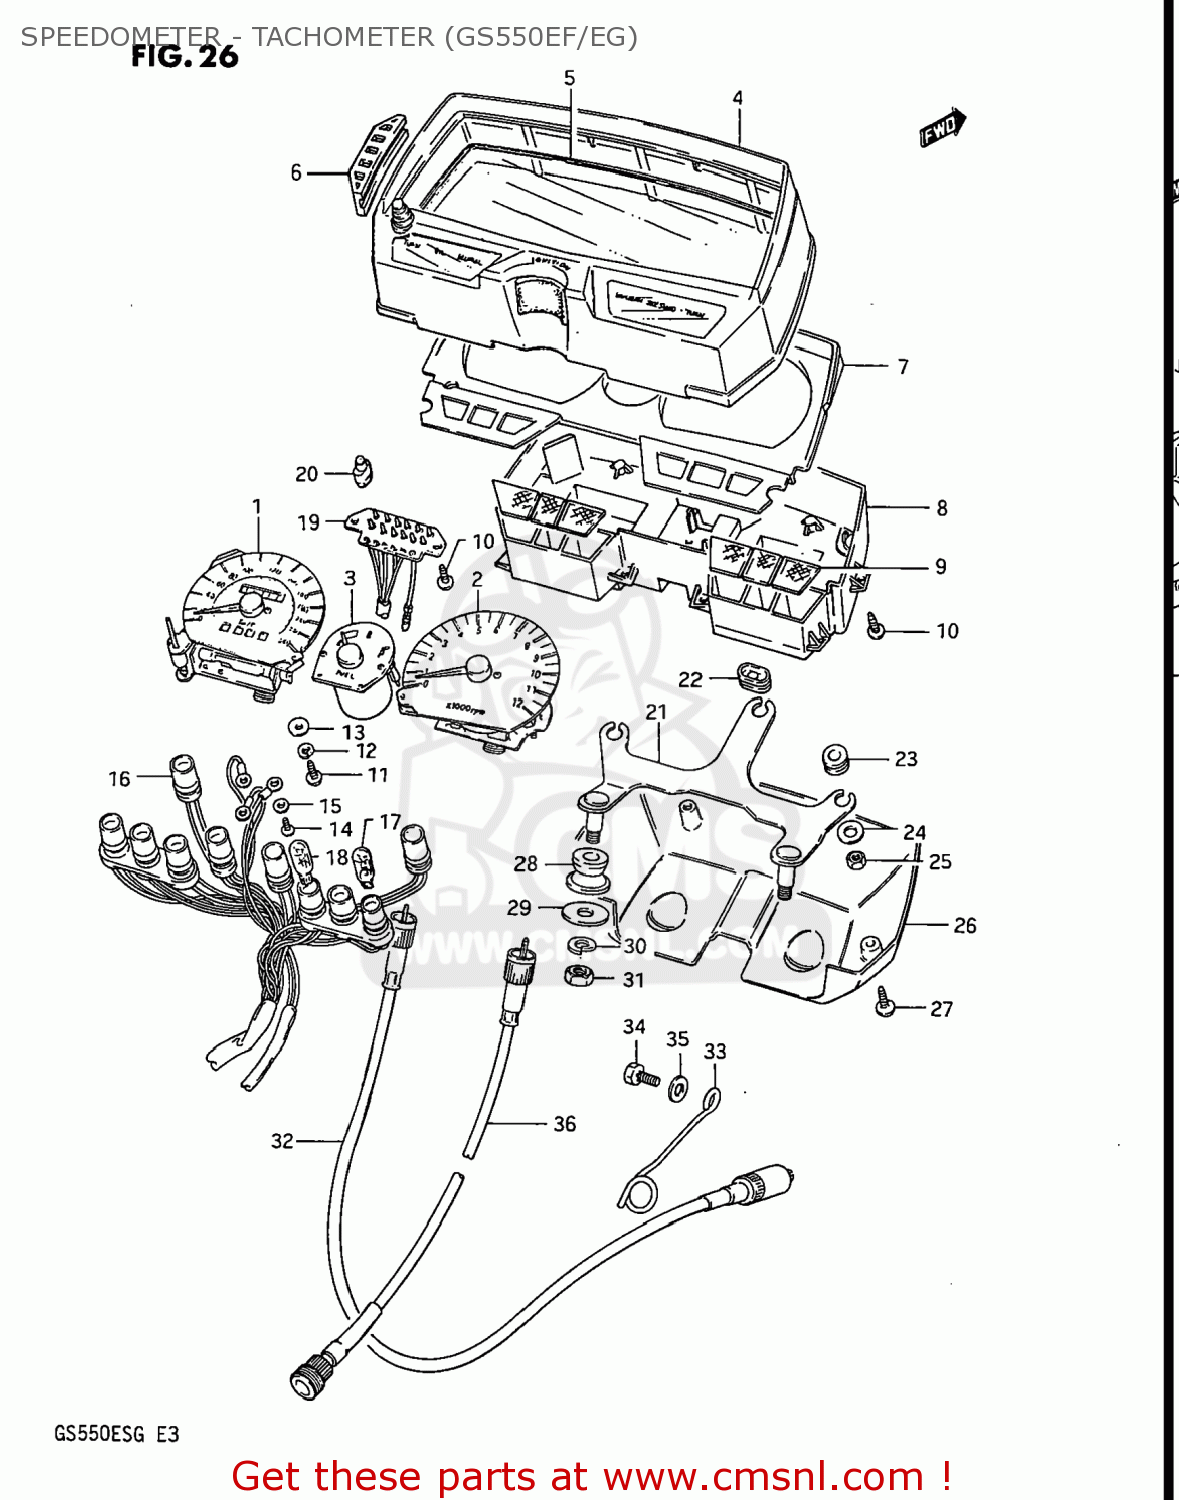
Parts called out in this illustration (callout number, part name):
1	METER,SPEEDOMETER (KM/MPH)
2	METER,TACHOMETER
3	METER,FUEL
4	HOOD,METER
5	GLASS,SPEEDOMETER
6	CUSHION,METER CASE
7	PLATE,METER WINDOW
8	CASE,METER,INNER
9	LENS SET,PILOT
10	SCREW,GEAR INDICATOR
11	SCREW
12	LOCK WASHER
13	WASHER
14	SCREW
15	WASHER
16	SOCKET
17	BULB(12V3.4W,T10,BF175-01450A)
18	BULB(12V1.7W,T10,WB121)
19	SOCKET,GEAR INDICATOR
20	BULB(14V1.12W)
21	BRACKET,METER
22	CUSHION,METER
23	CUSHION,METER
24	WASHER,METER
25	NUT
26	COVER,METER,UNDER
27	SCREW
28	CUSHION,METER BRACKET
29	WASHER (8.5X20X1.6)
30	WASHER,LOCK,8.
31	NUT
32	CABLE ASSEMBLY,SPEEDOMETER
33	CLAMP,SPEEDOMETER CABLE
34	BOLT, UPPER
35	WASHER
36	CABLE ASSY,TACHOMETER
